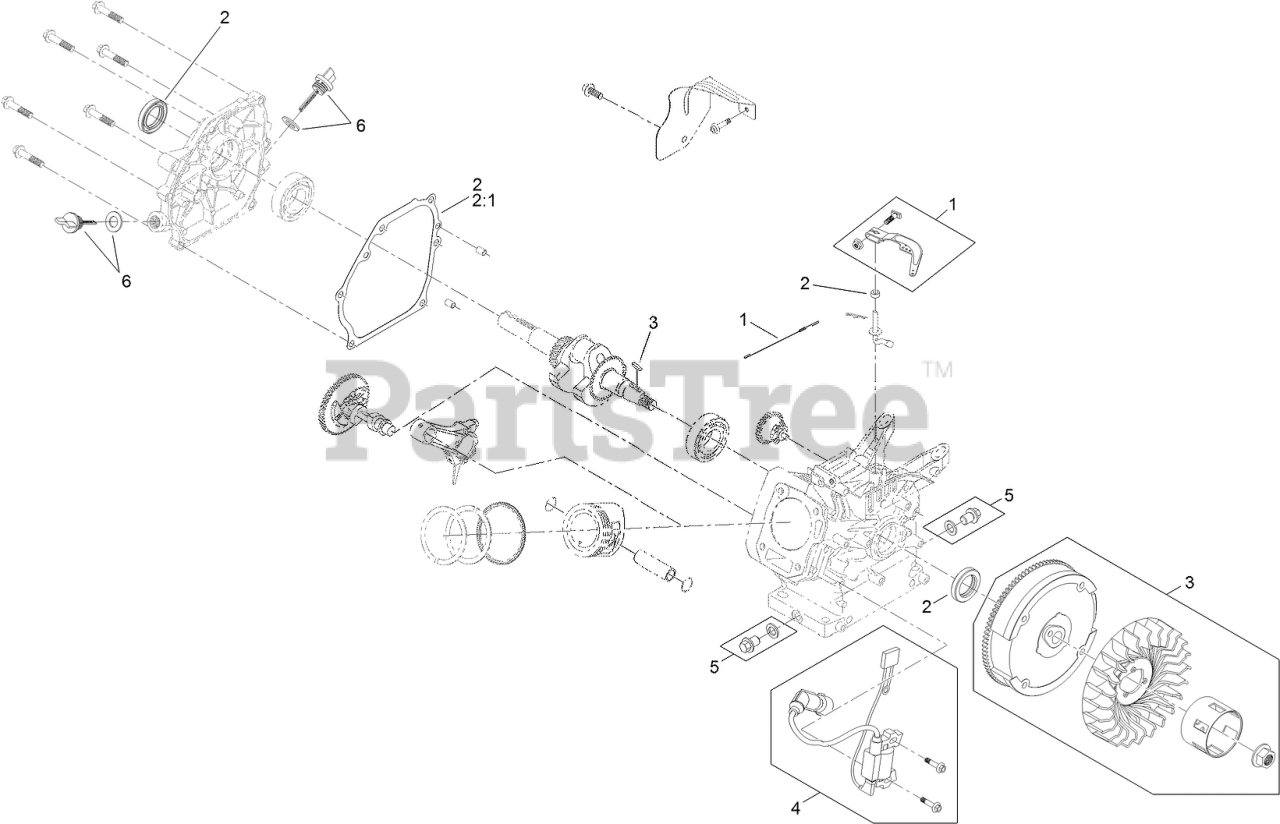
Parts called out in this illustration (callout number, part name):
1	GOVERNOR KIT
2	GASKET AND SEAL KIT
2:1	GASKET-COVER, VALVE
3	FLYWHEEL KIT
4	IGNITION KIT
5	DRAIN PLUG KIT
6	OBS DIPSTICK AND O-RING KIT
